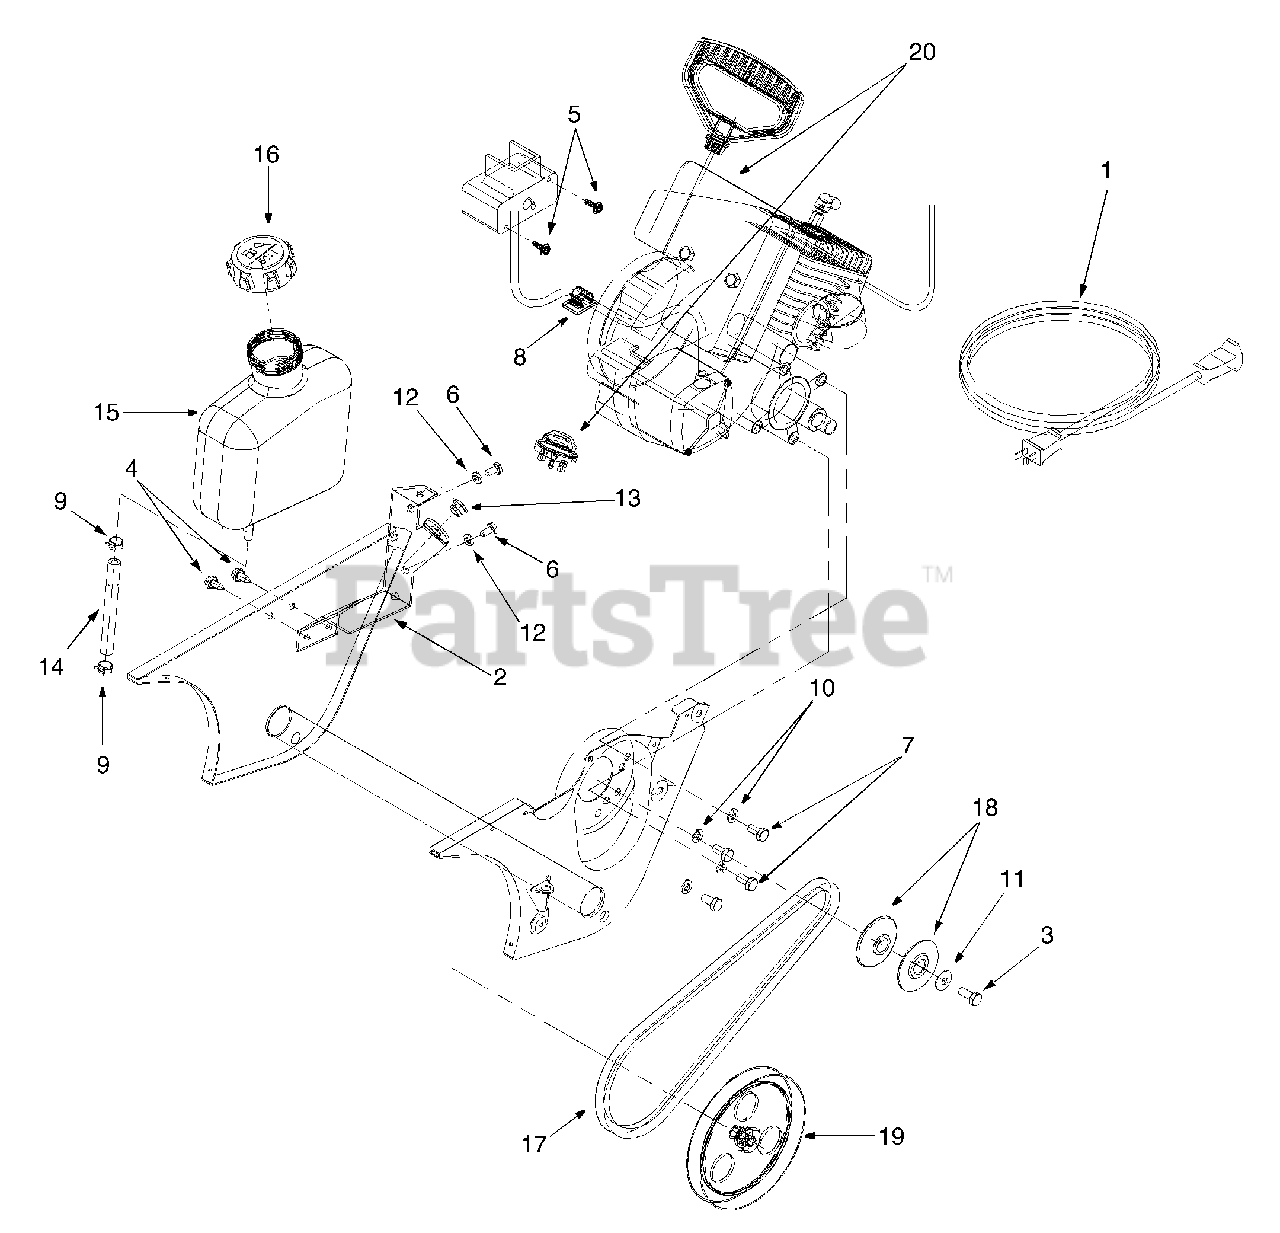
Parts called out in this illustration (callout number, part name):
1	Cord-Extension
4	Screw-Washer
5	Screw-Hex
6	Screw-Hex
7	Screw-Hex Cap
8	Clamp-Mounting
9	Clamp-Hose
10	Washer-Lock
11	Washer-Bell
12	Washer-Lock
13	Bushing
14	Hose-Fuel
16	Cap-Fuel
17	V-Belt
18	V-Pulley-Half
